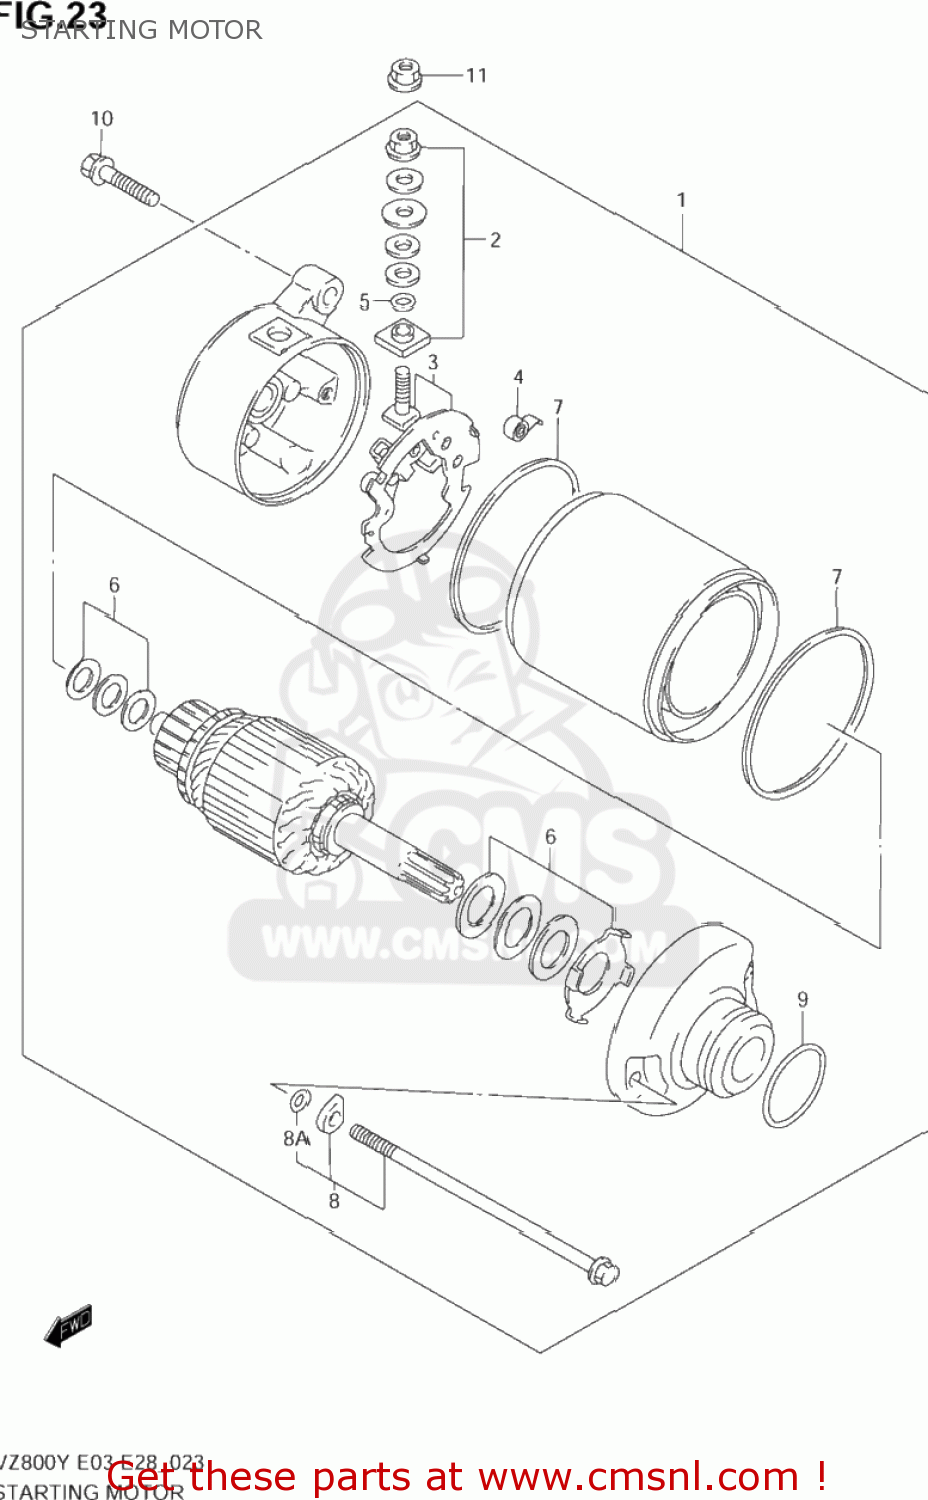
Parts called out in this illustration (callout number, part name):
1	MOTOR ASSY,STARTING
2	TERMINAL SET,BRUSH,PLUS
3	HOLDER SET,BRUSH
4	SPRING,BRUSH
5	O RING
6	SHIM SET,STARTING MOTOR
7	O RING
8	BOLT SET,STARTING MOTOR
8A	O RING
9	O RING(D:3,ID:24.5)
10	BOLT
11	NUT
